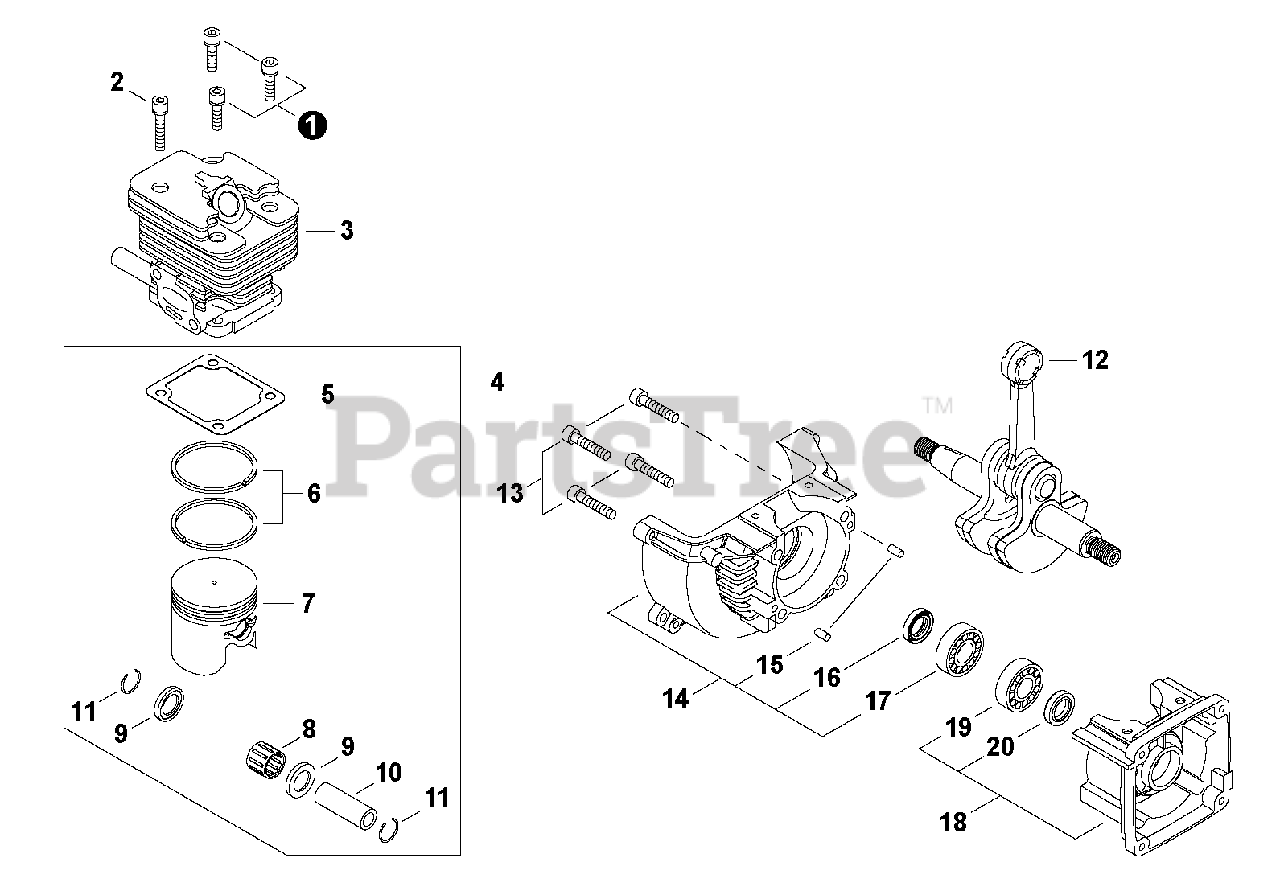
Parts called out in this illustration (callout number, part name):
1	BOLT M5×16
3	CYLINDER
4	PISTON KIT
5	GASKET, CYLINDER
6	RING, PISTON
8	BEARING, NEEDLE
9	WASHER, THRUST 9
10	PIN, PISTON
11	RING, SNAP
12	CRANKSHAFT ASSY
13	BOLT 5×25
14	CRANKCASE ASSY, M
15	PIN, LOCATING 5×10
16	SEAL, OIL 12
17	BEARING, BALL 6201 C3
18	CRANKCASE ASSY, S
19	BEARING, BALL 6201 C3
20	SEAL, OIL 12
